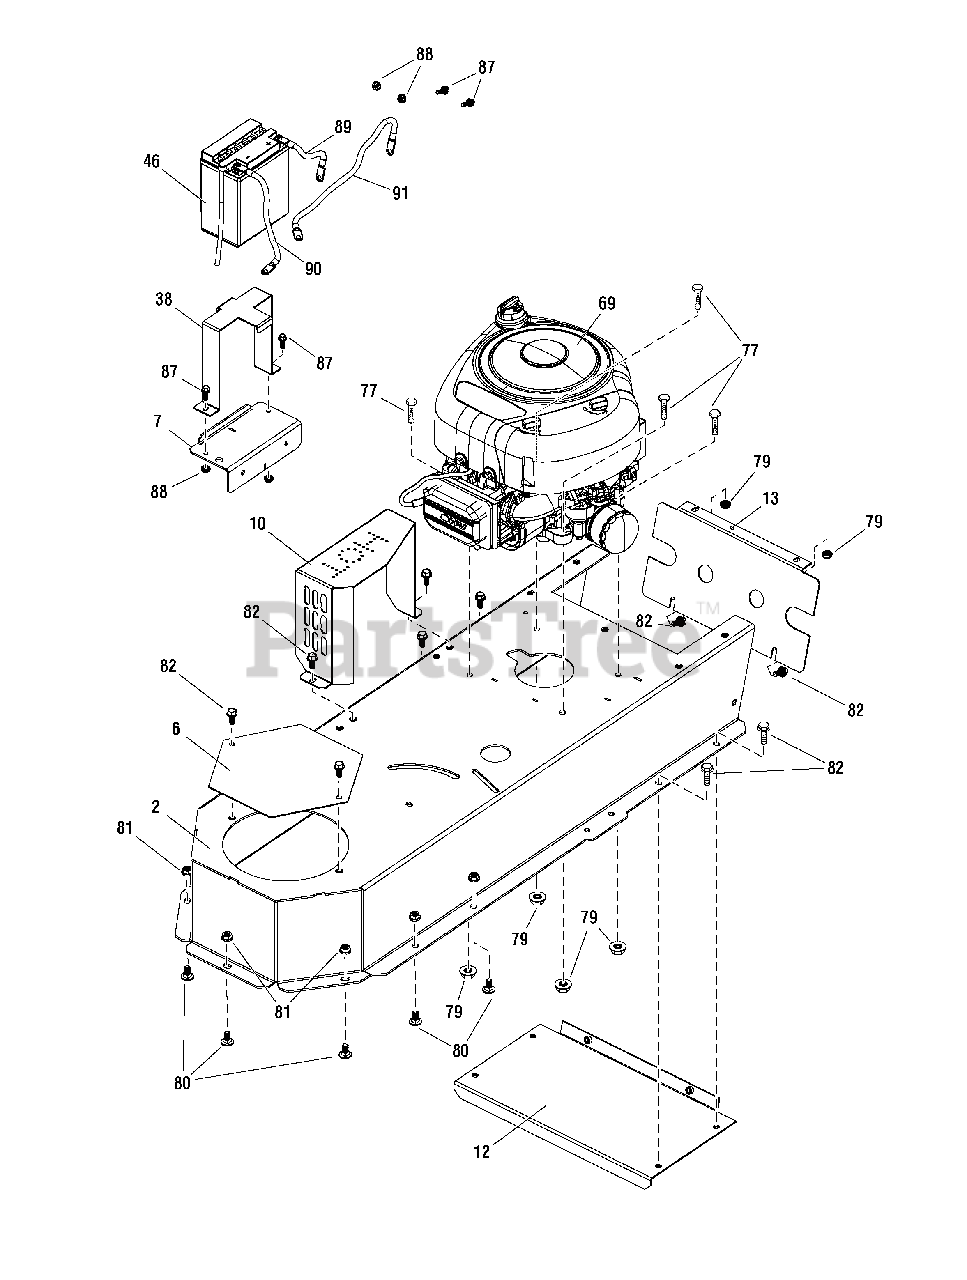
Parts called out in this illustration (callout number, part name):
2	ENGINE DECK
6	COVER, BLADE SPINDLE
7	BATTERY TRAY
10	EXHAUST SHIELD
12	BOTTOM GUARD
13	REAR GUARD
38	BATTERY HOLD-DOWN
46	BATTERY, WITH ACID PACK
69	* ENGINE, 11.5hp Briggs & Stratton INTEK
69	* ENGINE, 17.5hp Briggs & Stratton INTEK
77	BOLT, 5/16"-18 X 1-1/2"
79	HEX NUT, SERRATED, 5/16"-18
80	CARRIAGE BOLT, 3/8"-16 X 3/4"
81	FLANGED LOCK NUT, 3/8"-16
82	BOLT, 5/16"-18 X 3/4"
88	NUT, 1/4"-20
89	BATTERY CABLE, RED, 8"
90	BATTERY CABLE, BLACK, 13"
91	BATTERY CABLE, RED, 16"
